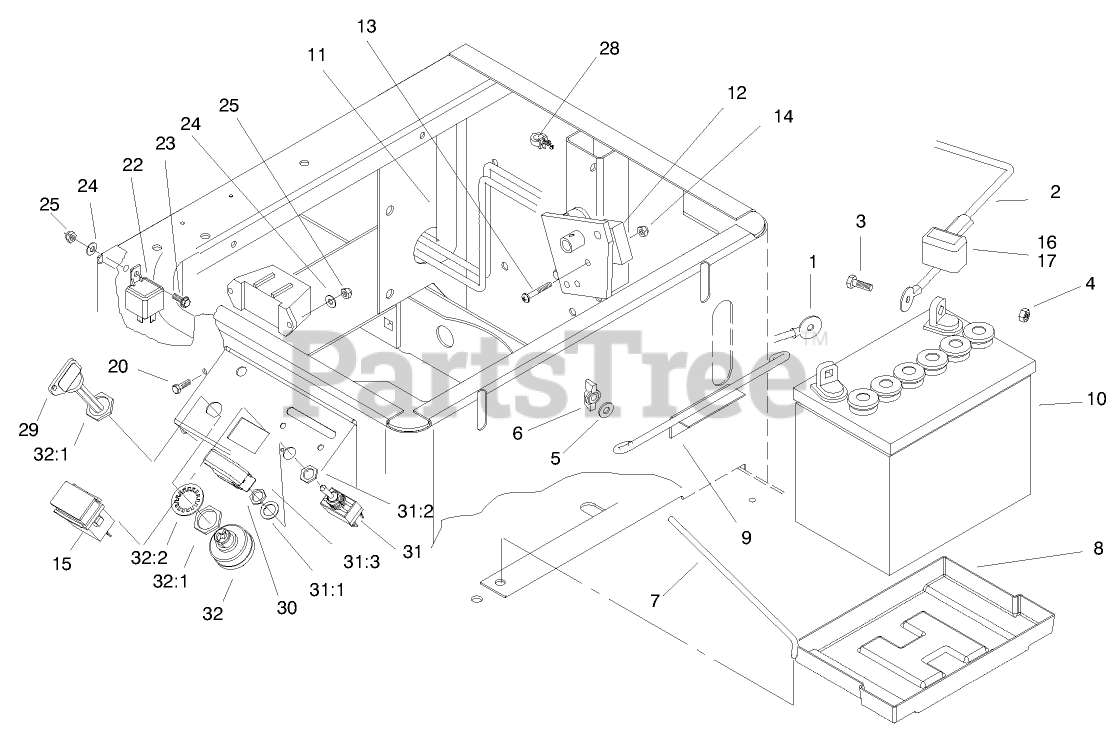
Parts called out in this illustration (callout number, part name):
1	WIRE ASM
2	WIRE ASM
3	SCREW-HH
4	NUT-LOCK, NI
5	WASHER-FLAT
6	NUT-WING
7	HOOK-BATTERY RETAIN
8	TRAY-BATTERY
9	HOLDDOWN-BATTERY
10	Battery
11	WIRE HARNESS ASSY
12	SWITCH-ASS'Y NEUTRAL
13	SCREW-PPH
14	NUT-LOCK, NI
15	HOURMETER
16	BOOT-TERMINAL, BLACK
17	BOOT-TERMINAL, RED
22	RELAY
23	SCREW-SHWH
24	WASHER-FLAT
25	NUT-LOCK, NI
28	CLIP-SNAP IN
29	KEY-IGNITION
30	COVER-PTO SWITCH
31	SWITCH-TOGGLE, SEALED
31:1	NUT-HEX, SPECIAL
31:2	TAB-WASHER
32	IGNITION SWITCH ASM
32:2	WASHER-LOCK
